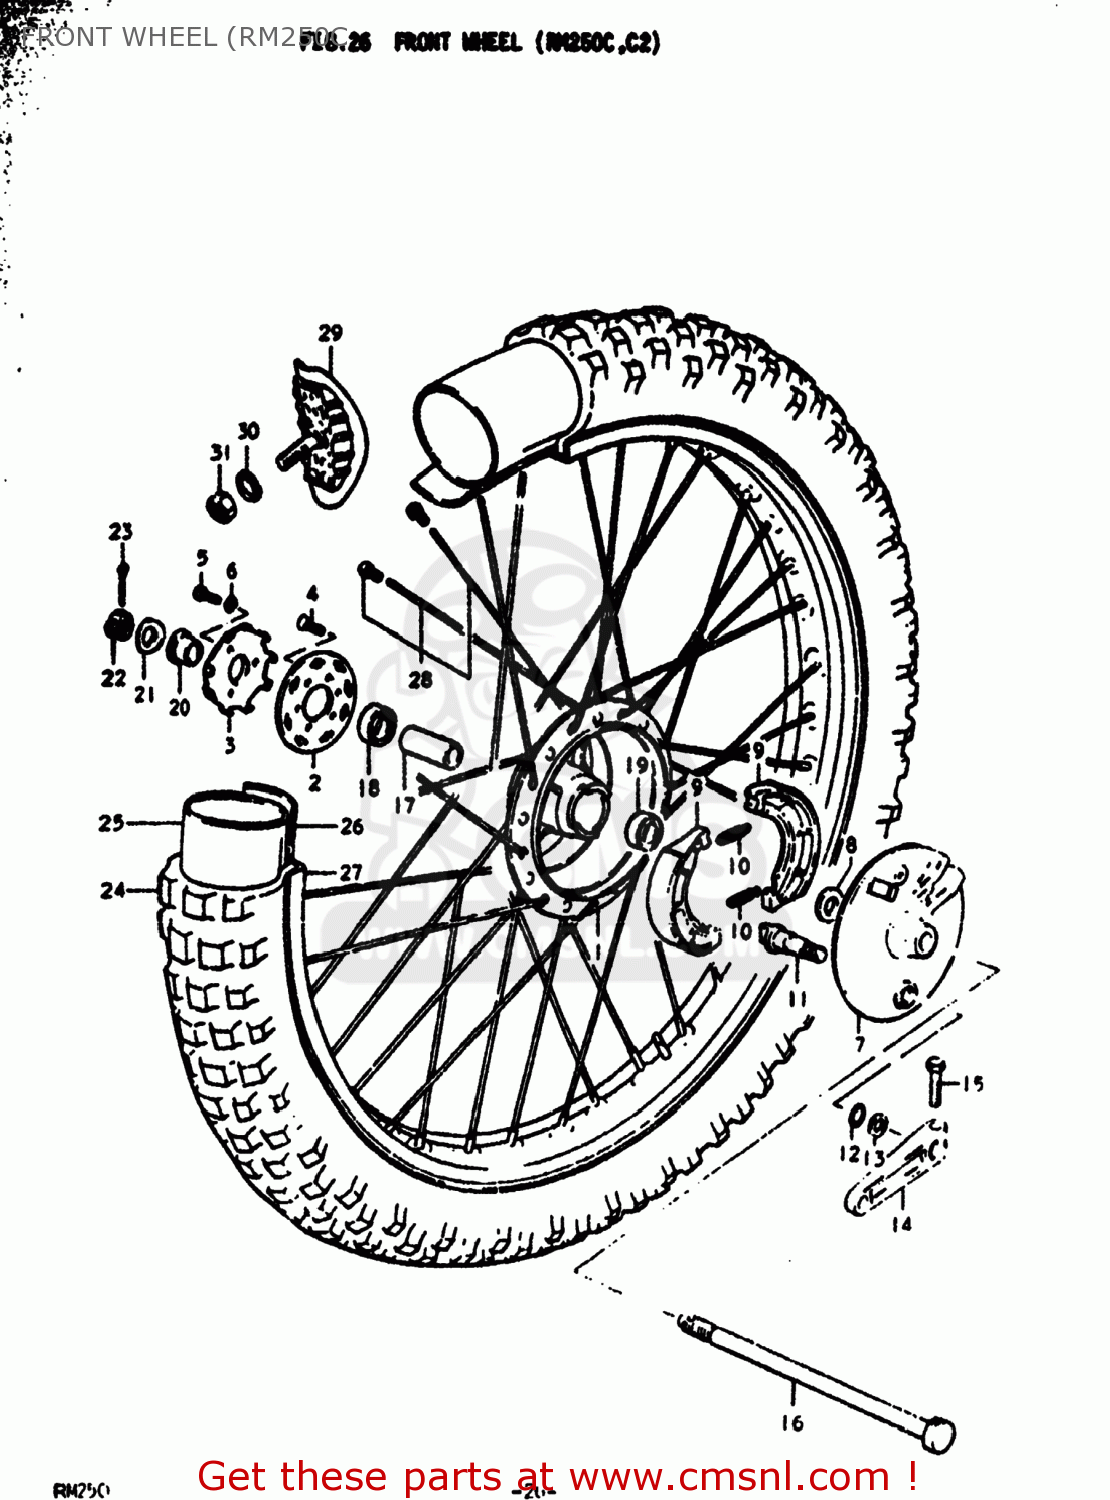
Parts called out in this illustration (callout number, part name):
1	HUB,FRONT
2	FLANGE,FRONT HUB,RIGHT
3	RETAINER,FR HUB BEARING,R
4	SCREW
5	BOLT, UPPER
6	LOCK WASHER
7	PANEL,FRONT HUB
8	BOSS
9	SHOE,BRAKE
10	SPRING(L:34)
11	CAM,FRONT BRAKE
12	O RING(D:2.5,ID:11.4)
13	WASHER(12.5X20X1)
14	LEVER,FRONT BRAKE CAM
15	BOLT
16	AXLE,REAR
17	SPACER (12.6X19X52)
18	BEARING
19	BEARING, LH
20	SPACER,FR AXLE,R
21	WASHER
22	NUT, REAR AXLE
23	COTTER PIN
24	TIRE,FRONT
25	TUBE
26	PROTECTOR,WHEEL,INNER
27	RIM,FRONT WHEEL
28	SPOKE SET,FRONT
29	STOPPER,BEAD
30	WASHER
31	NUT
